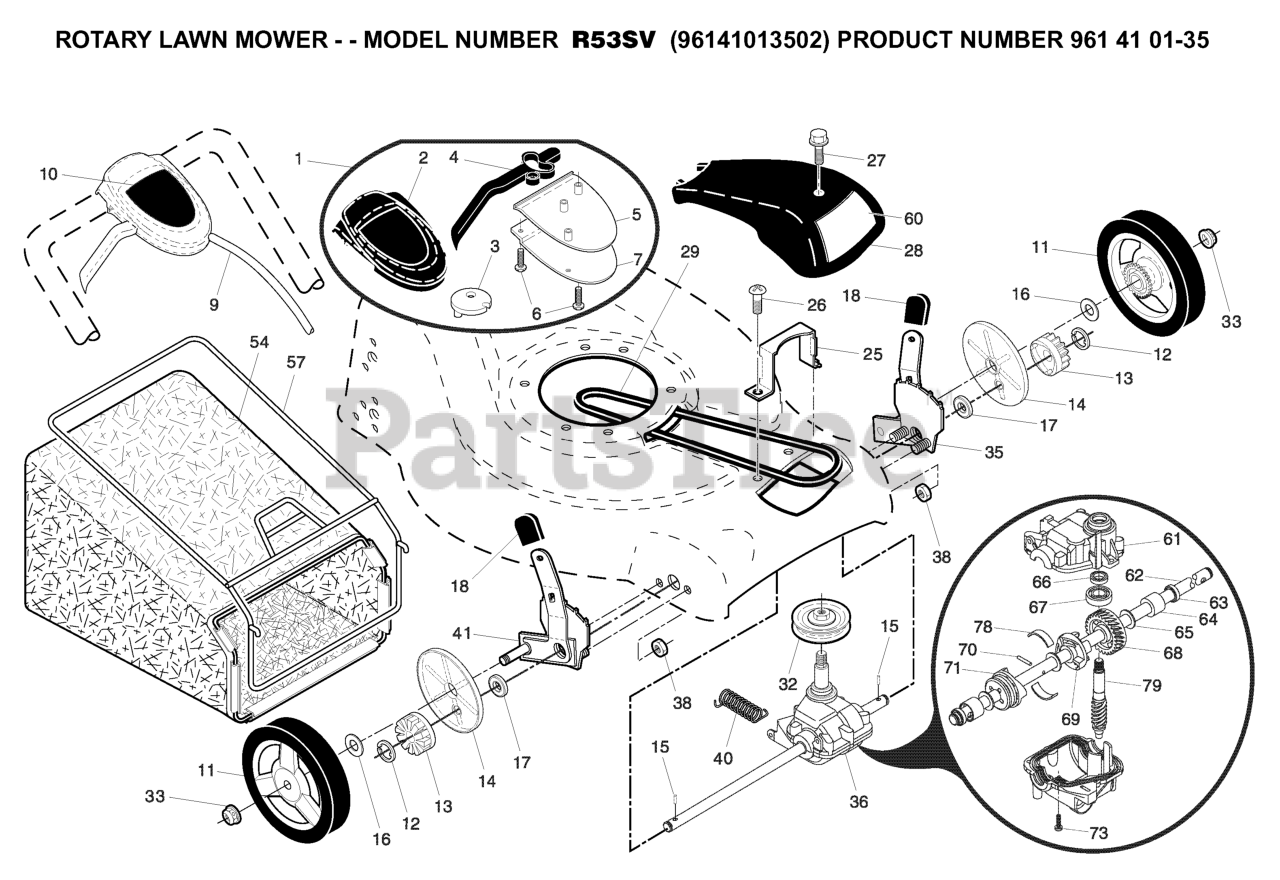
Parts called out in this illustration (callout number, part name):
1	DRIVE CONTROL ASSEMBLY (INCLUD
2	COVER TOP AUTO WALK CONTROL
3	PULLEY.CAM.DRIVE.CONTROL.EZ
4	LEVER, AUTOWALK DRIVE CONTROL
5	COVER BOTTOM AUTO WLK CONTROL
6	SCREW, PHILLIPS HEAD 10 X 5/8
7	BRACKET.DRIVE.CONTROL.MOUNT.BL
9	CABLE ASSEMBLY, DRIVE
11	WHEEL.8X1.75.MAG2.RAD3.GRY
12	E-RING 7/16 RE
13	PINION.14.TEETH.FGD
14	COVER.DUST.WHEEL
15	PAWL, DRIVE
16	WASHER FLUT
17	BEARING ASM
18	SELECTOR KNOB
25	BELT KEEPER
27	SCREW, HEX HD TAPPING #10-24 1
28	COVER.DRIVE.21.FWGD.GRAY
29	BELT.DRIVE.FG
32	RP PULLEY.DRIVE.EZ
33	NUT.HEX.FLANGE.3/8-16.LO(3 2)
36	TRANSMISSION.21.FGD.HT.VST
38	LOCKNUT.NYLOC.1/4-20
54	Grassbag Assembly
57	FRAME, GRASSBAG
60	DECAL DRIVE COVER
61	CASE.UPPER.00254(SERVICE)
62	SHAFT OUTPUT (12289)
63	SEAL.OUTPUT.SHAFT
66	SEAL INPUT SHAFT
68	GEAR 28 TEETH 36208
69	FIXED DOG CLUTCH
70	PIN.3.50.33733
71	MOVEABLE DOG CLUTCH
74	CASE.BOTTOM.
78	SPRING LEAF
79	SHAFT WORM
